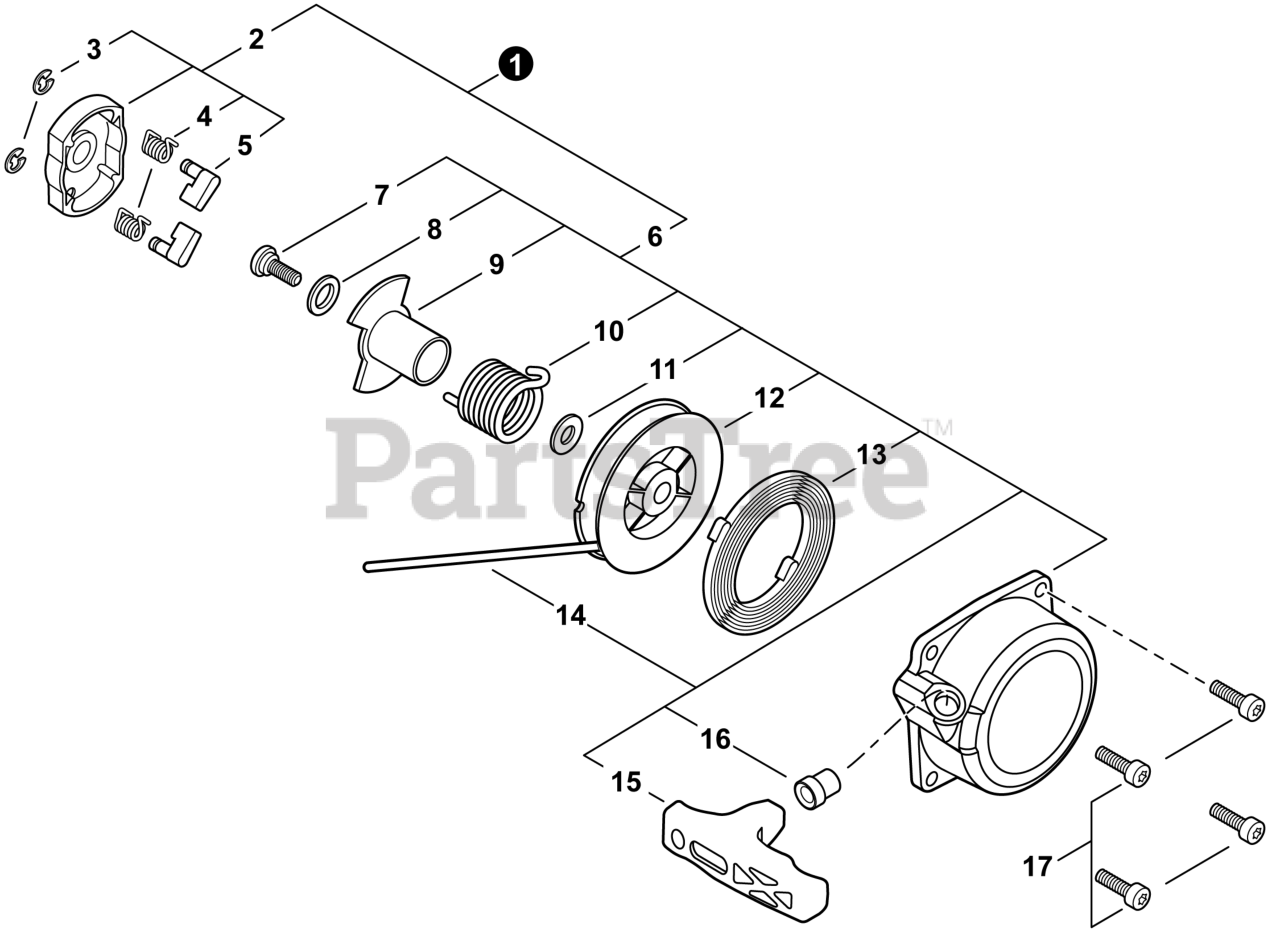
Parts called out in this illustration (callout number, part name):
1	STARTER & PAWL SET
2	PAWL ASSY, STARTER
3	E-RING 4
4	SPRING, RETURN
5	PAWL, STARTER
6	STARTER ASSY, RECOIL
7	SCREW
8	WASHER, THRUST
9	PAWL CATCHER
10	SPRING
11	WASHER
12	REEL, ROPE
13	SPRING, SPIRAL
14	ROPE, STARTER
15	GRIP, STARTER
16	GUIDE, ROPE
17	BOLT, TORX 5x20
